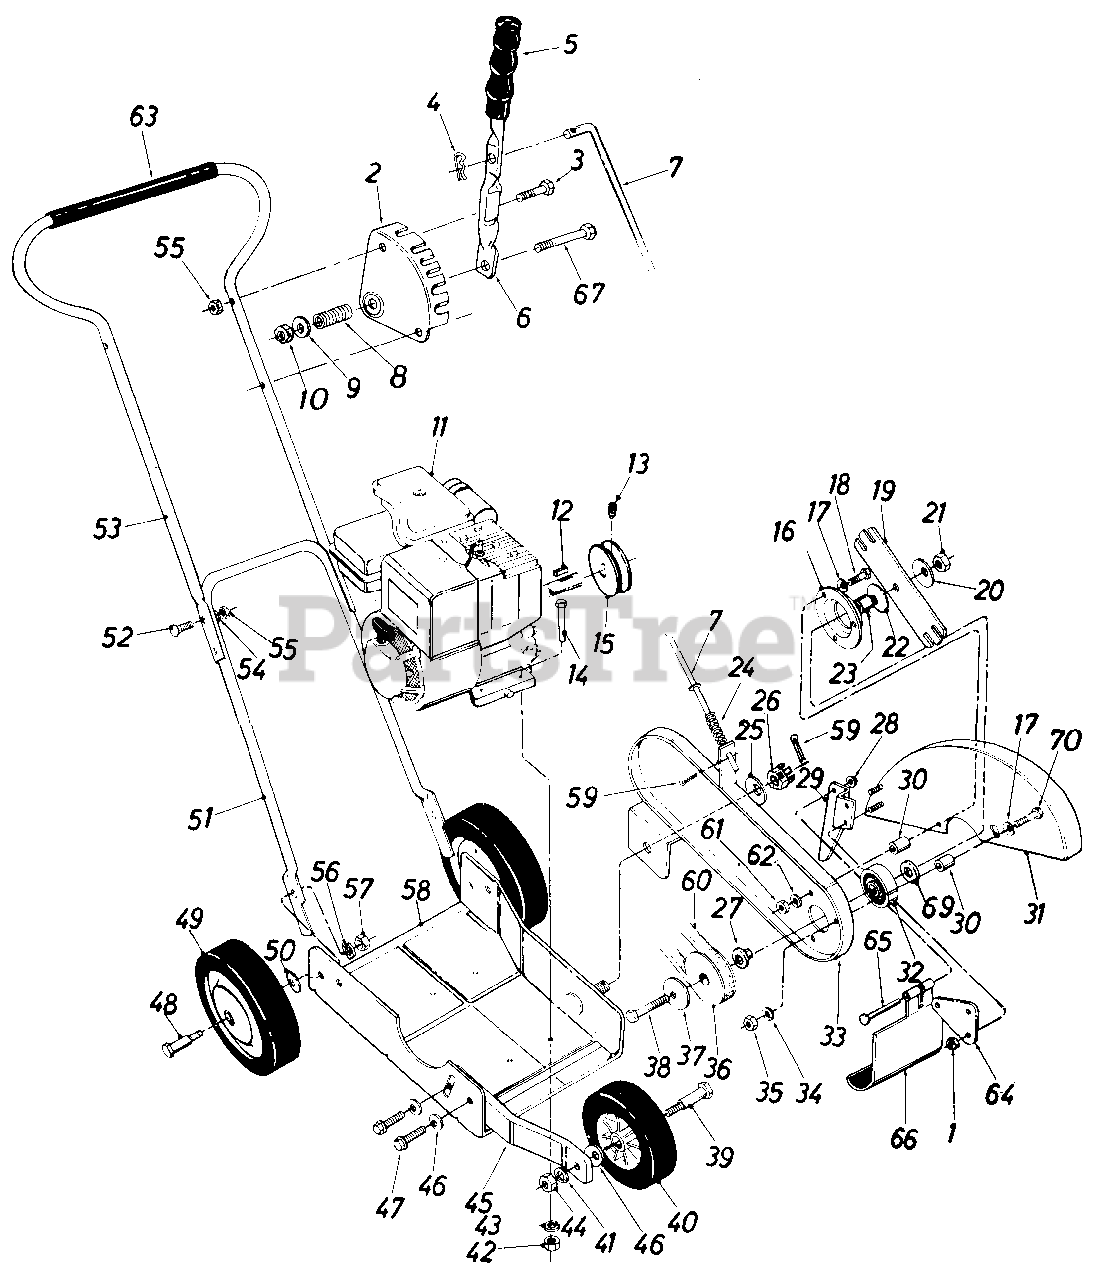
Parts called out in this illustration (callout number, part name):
1	Hex Cent. L. Nut 1/4-20 Thd.
3	Hex Bolt 1/4 20 x 1.25" Lg.
4	CotterPin 1/8" Dia. x 1.0" Lg.
5	Grip
7	Clutch Rod
8	Compression Spring .50" 0.D. x 1.38" Lg.
9	Fl.-Wash. .34" I.D. x .62" O.D. x.063
10	Hex Cent. L. Nut 5/16-18 Thd.
11	Engine
12	Sq. Key 3/16 x 1.0" Lg.
13	Set Scr. 1/4-28 x 1/4" Lg.
14	Hex Bolt 5/16 18 x 1.50" Lg.
15	Engine Pulley
16	Bearing Housing
17	Bell.-Wash. .34" I.D. x 88" O.D. x .060
18	Hex Bolt 5/16-18 x 1.25" Lg.
20	Bell. Wash. .535" I.D. x 1.50" O.D. x.052
21	Hex Cent. L.-Nut 1/2-20 Thd.
22	Bell.-Wash. .535" I.D. x 1.50" O.D. x .052
23	Spacer
24	Compression Spring .57" O.D. x 1.92" Lg.
25	Bell.-Wash. .535" I.D. x 1.50" O.D. x .052
26	Hex Castle Nut 1/2-20 Thd.
27	Shoulder Spacer
28	Push Cap
29	Guide
30	Spacer.354" I.D. x .635" O.D. x .510" Lg.
33	Spindle Bracket Ass'y.
34	L.-Wash. 5/16" I.D.
35	Hex Nut 5/16-18 Thd.
36	1 Pulley Half
37	Bell.-Wash. .535" I.D. x 1.50" O.D. x .052
38	Hex Bolt 1/2-20 x 3.50" Lg.
39	Shoulder Bolt .498" Dia. x 1 .450
40	Wheel Ass'y. Comp. 6" Dia. x 1.50
41	L.-Wash. 3/8" I.D.
42	Hex Nut 5/16-18 Thd.
43	L.-Wash. 5/16" I.D.
44	Hex Nut 3/8-16 Thd.
45	Front Wheel Support
46	Bell.-Wash. .400" I.D. x 88" 0. D. x .060
47	Hex Wash. Hd. Self Tap Scr. 3/8- 1 6 x .75" Lg.
48	Shoulder Bolt .498" Dia. x 1 .450
49	Wheel Ass y. Comp. 7" Dia. x 1.50
50	Bell.-Wash. .400" I.D. x 88" 0. D.
51	Lower Handle
52	Carriage Bolt 1/4-20 x 1.25" Lg.
53	Upper Handle
54	L.-Wash. 1/4" I.D.
55	Hex Nut 1/4-20 Thd.
56	L.-Wash. 3/8" I.D.
57	Hex Nut 3/8-16 Thd.
58	Base Ass'y.
59	Cotter Pin 1/8" Dia. x 1.0" Lg.
60	3V-Belt 31.2" Lg.
61	Hex Nut 5/16-18 Thd.
62	L.-Wash. 5/16" I.D.
63	Grip
64	Flap Bracket
65	Hinge Pin
66	Debris Deflector
67	Hex Bolt 5/16-18 x 1.75" Lg.
69	Fl.-Wash. .51 I.D. x 1.00 O.D. x.060
70	Hex Bolt 5/16-18 x 2.00" Lg.
